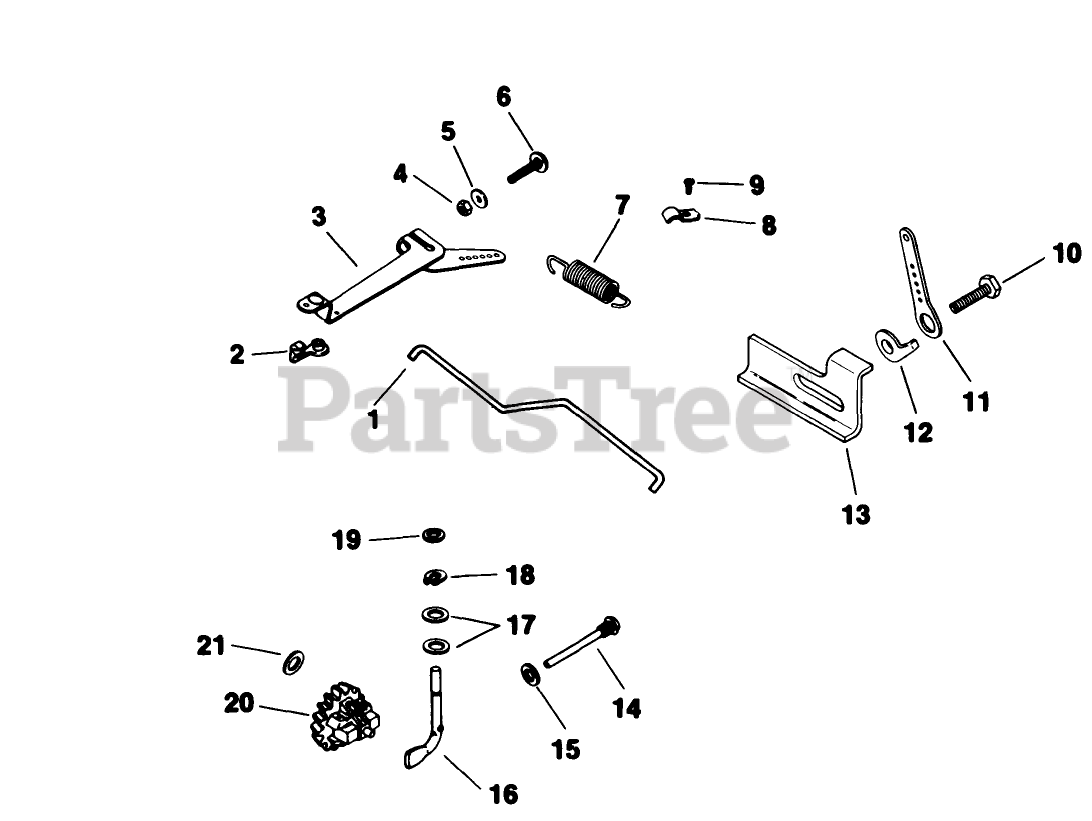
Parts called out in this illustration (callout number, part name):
1	Kit-Governor Linkage (Incl. Ref. #2)
2	Bushing
3	Arm-Governor
5	Washer
6	Screw-Round Hd.
7	Spring-Governor
8	Clip
9	Screw
10	Screw
11	Lever-Speed Control
12	Stop-Govenor
13	Stop-High Speed
14	Pin-GovemorStop
15	Washer
16	Shaft-Govenor
17	Washer
18	Retainer-Governor
19	Washer
20	Governor Gear
21	Washer
